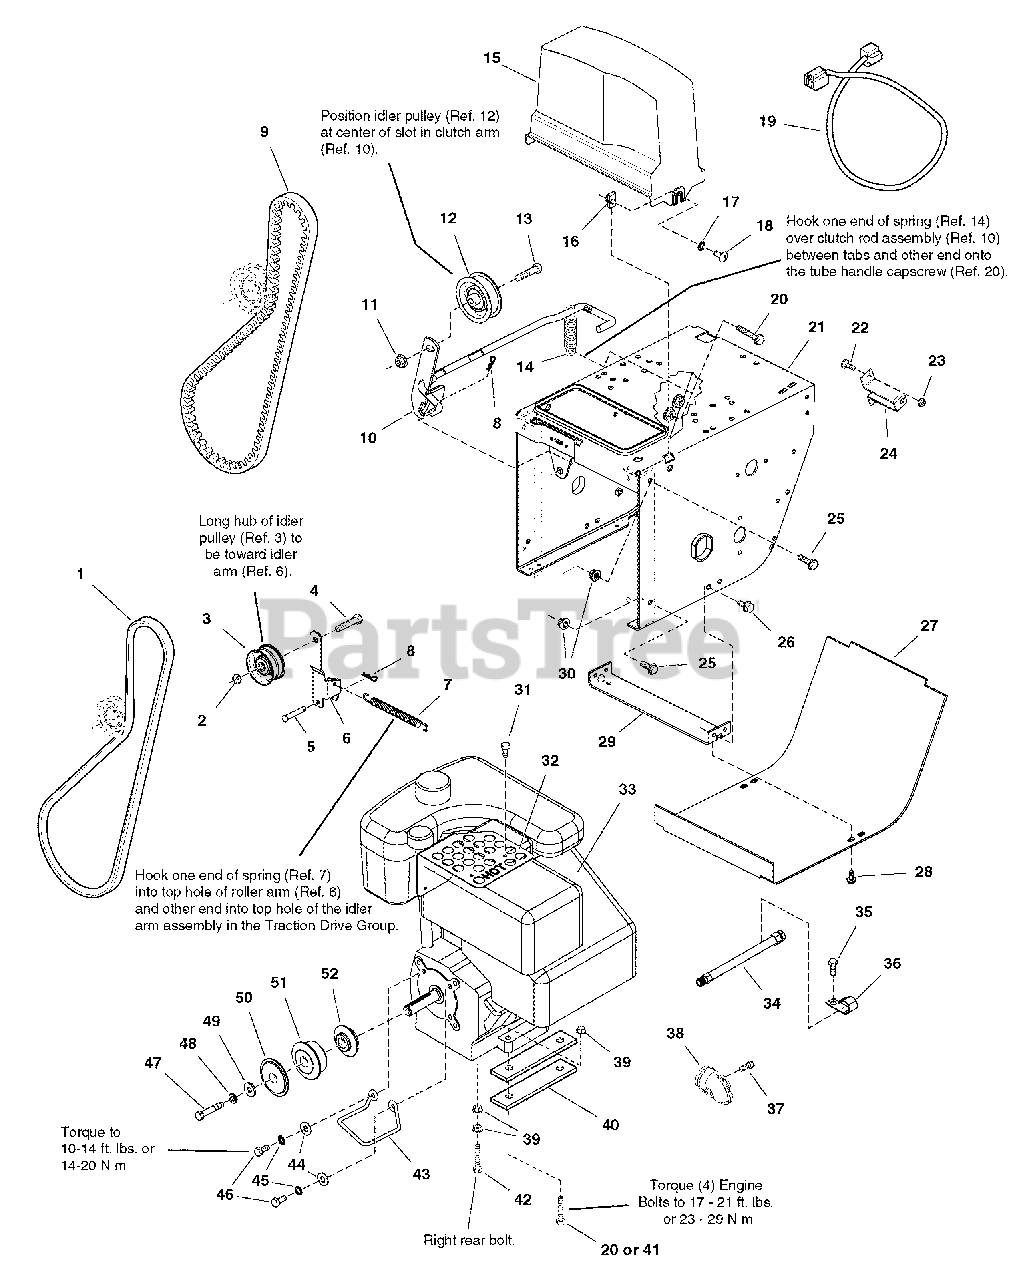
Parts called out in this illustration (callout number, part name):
1	V-BELT, 3L (Used on all models Except 1694859 models)
1	V-BELT, 3L (Used Only on 1694859 models)
2	NUT, Hex, Toplock, Jam, 3/8-16
3	PULLEY, Idler
4	SCREW, Hex Head, 3/8-16 x 1-1/2
5	PIN, Flat Head Drilled
6	ARM, Idler, 5-3/4 LG
7	SPRING, Extension
8	PIN, Quick
9	V-BELT, HA (Used on all models Except 1694859 models)
9	V-BELT, HA (Used Only on 1694859 models)
10	ROD AND ARM ASSEMBLY, Clutch, Brake
11	NUT, Hex Flange, 3/8-16 Whiz Lock Large
12	PULLEY, Idler
13	CAPSCREW, Hex Whiz Lock Flange, 3/8-16 x 1-3/4
14	SPRING, Extension, 4-1/4 Long
15	COVER, Belt
16	NUT, Speed, Lug Type, 5/16-18
17	LOCKWASHER, External Tooth, 5/16
18	SCREW, Truss head Slotted, 5/16-18 x 3/4
19	CORD, Electric Extension
20	CAPSCREW, Hex Head, 5/16-18 x 1-1/2 G5 (Quantity 3 used on 1694853 models)
21	FRAME ASSEMBLY, Chain/Tube Handles
22	CARRIAGE BOLT, 1/4-20 x 3/4 G5
23	NUT, Hex KEPS, 1/4-20, Conical Washer
24	SUPPORT, Clutch Cable, 16GA
25	SCREW, Hex Whiz Lock Flange, 5/16-18 x 3/4
26	SCREW, Hex Washer Head Taptite, 5/16-18 x 3/4
27	COVER, Bottom Frame, 20GA
28	SCREW, Hex Washer Head Taptite, 1/4-20 x 1/2
29	SUPPORT, Tie Bar
30	NUT, Hex Flange, 5/16-18, Whiz Lock Large
31	SCREW, Hex Washer Head Taptite, #10-24 x 1/2
32	GUARD, Muffler, 18GA
33	ENGINE, 10.5HP Briggs & Stratton Electric Start
34	HOSE, Oil Drain, w/Fittings
35	CAPSCREW, Hex Washer Head, 5/16-18 x 3/4
36	CLIP, "J"
37	SCREW, Muffler Deflector
38	DEFLECTOR, Rain Guard, B&S Snow Muffler
39	NUT, Hex Flange, 5/16-18, Whiz Lock Small (Quantity 4 used only on 1694853 models)
40	SUPPORT, Engine Riser, 3/8" Thick, 1-1/4 x 4-31/50 (Used on all models Except 1694853 models)
41	CAPSCREW, Hex Whiz Lock Flange, 5/16-18 x 2-1/4 (Used on all models Except 1694853 models)
42	CAPSCREW, Hex Washer Head Taptite, 5/16-18 x 2-1/2 (Used on all models Except 1694853 models)
42	SCREW, Hex Head Cap, 5/16-18 x 1 3/4
43	STOP, Belt
44	WASHER, 5/16
45	LOCKWASHER, Spring, 5/16
46	CAPSCREW, Hex Head, 5/16-24 x 3/4 G5
47	CAPSCREW, Hex Head, 3/8-24 x 1-1/2 G8
48	LOCKWASHER, Spring, 3/8
49	WASHER, 3/8
50	PULLEY, Engine Outside, Powdered Metal
51	PULLEY, Engine Middle, Powdered Metal
52	PULLEY, Half Powdered Metal
